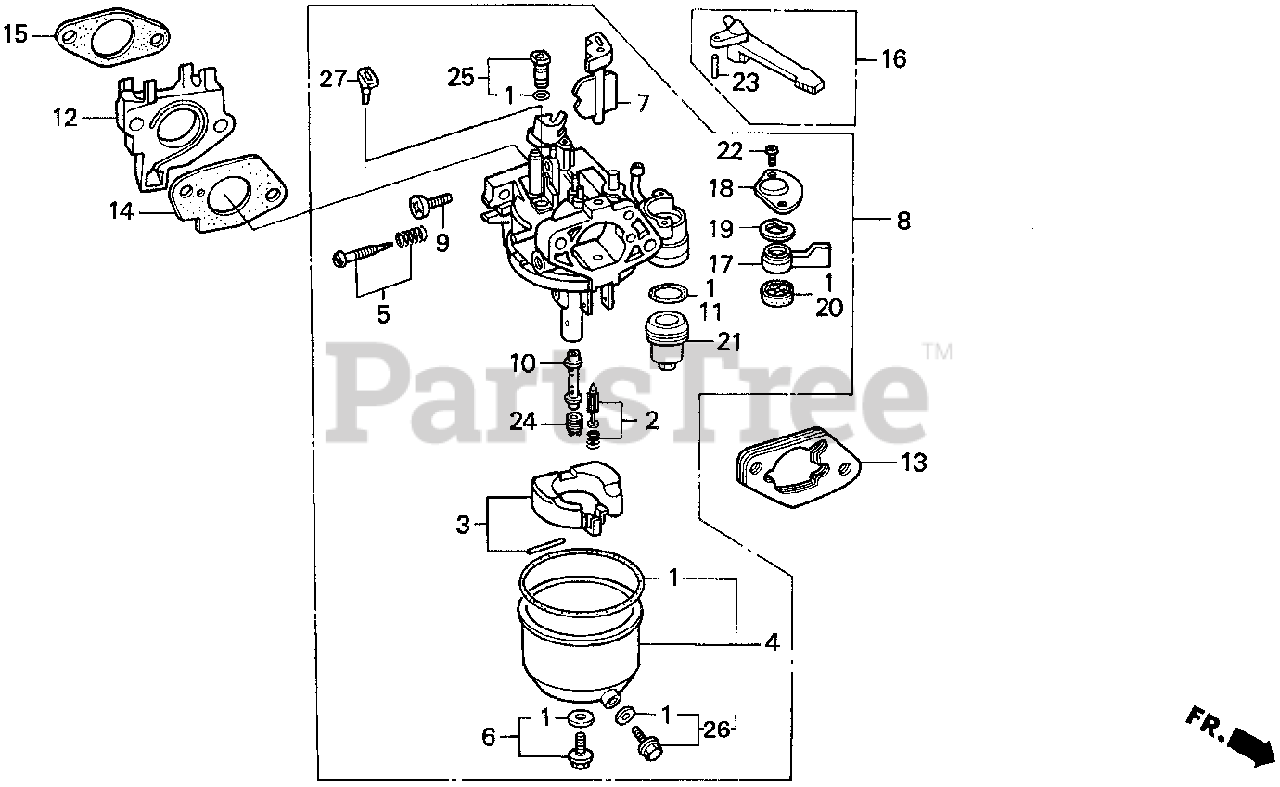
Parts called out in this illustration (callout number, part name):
1	GASKET SET
2	VALVE SET, FLOAT
3	FLOAT SET
4	CHAMBER SET, FLOAT
5	SCREW SET, PILOT
6	SCREW SET B
7	CHOKE SET
8	CARBURETOR ASSY. (BE21A B)
8	CARBURETOR ASSY. (BE21A C)
9	SCREW, THROTTLE STOP
10	NOZZLE, MAIN
11	GASKET, FUEL STRAINER CUP
12	INSULATOR, CARBURETOR
13	SPACER, CARBURETOR
14	GASKET, CARBURETOR
15	GASKET, INSULATOR
16	LEVER, CHOKE (STD)
17	LEVER, VALVE
18	PLATE, LEVER SETTING
19	SPRING, VALVE LEVER
20	GASKET, VALVE
21	CUP, FUEL STRAINER
22	SCREW, PAN (3X6)
22	SCREW, PAN (3X8)
23	PIN, SPRING (2X12)
24	JET, MAIN (#82)
24	JET, MAIN (#85)
24	JET, MAIN (#88)
25	JET SET, PILOT (#40)
